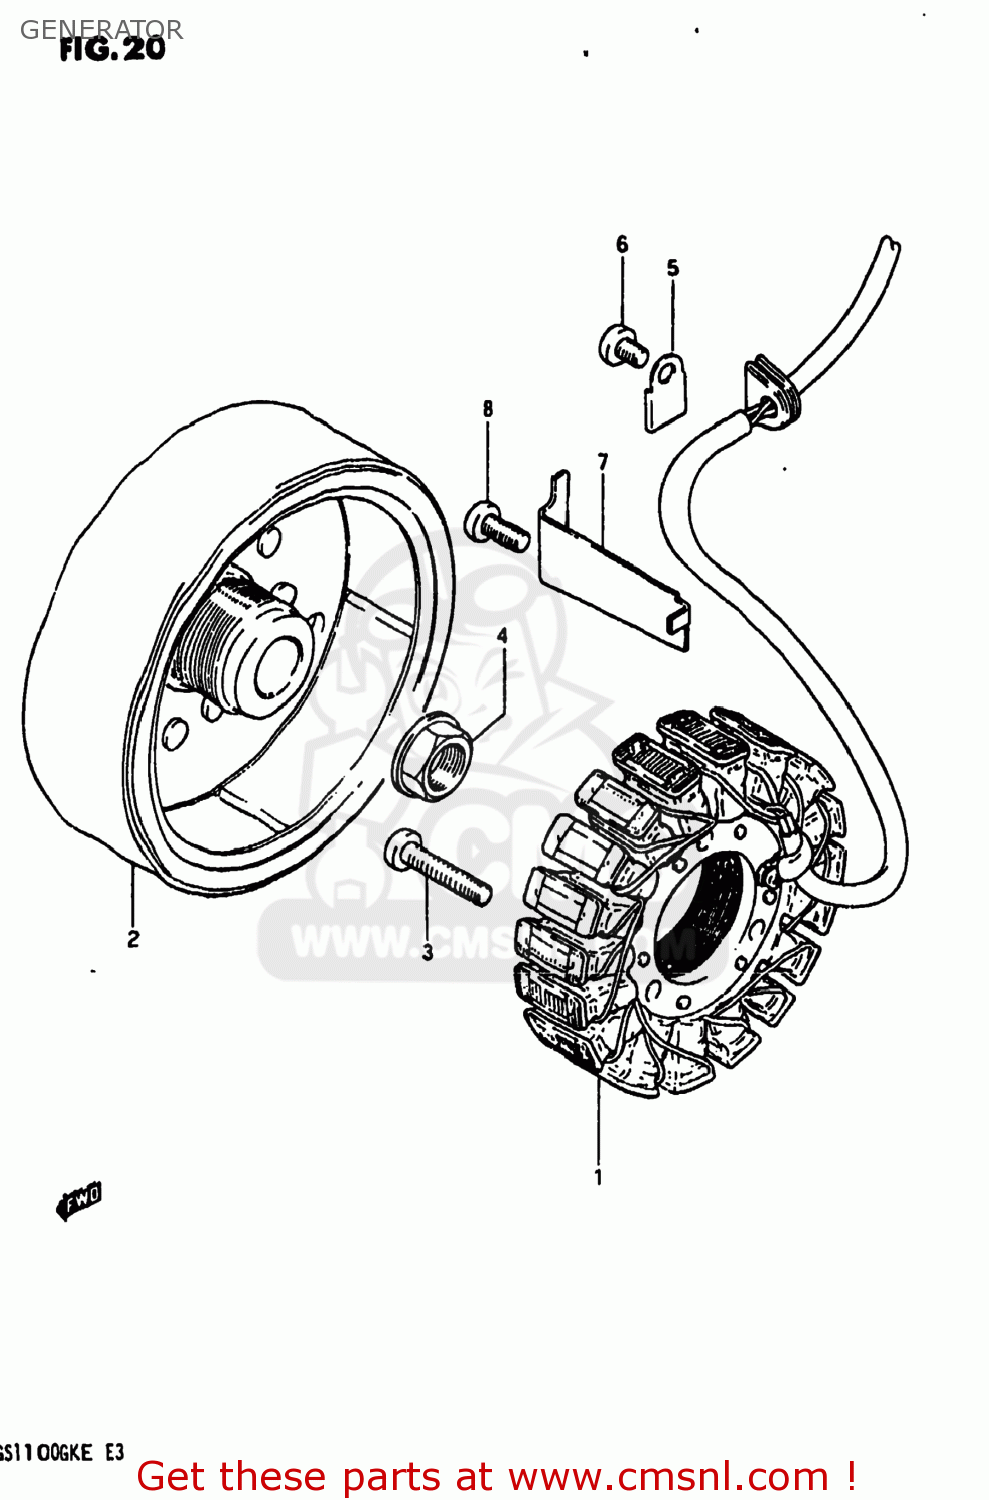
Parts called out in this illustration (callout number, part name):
1	STATOR ASSEMBLY
2	ROTOR ASSEMBLY
3	SCREW 6X30
4	NUT,GENERATOR ROTOR
5	CLAMP,GENERATOR LEAD WIRE
6	SCREW
7	CLAMP,GENERATOR LEAD WIRE
8	SCREW
